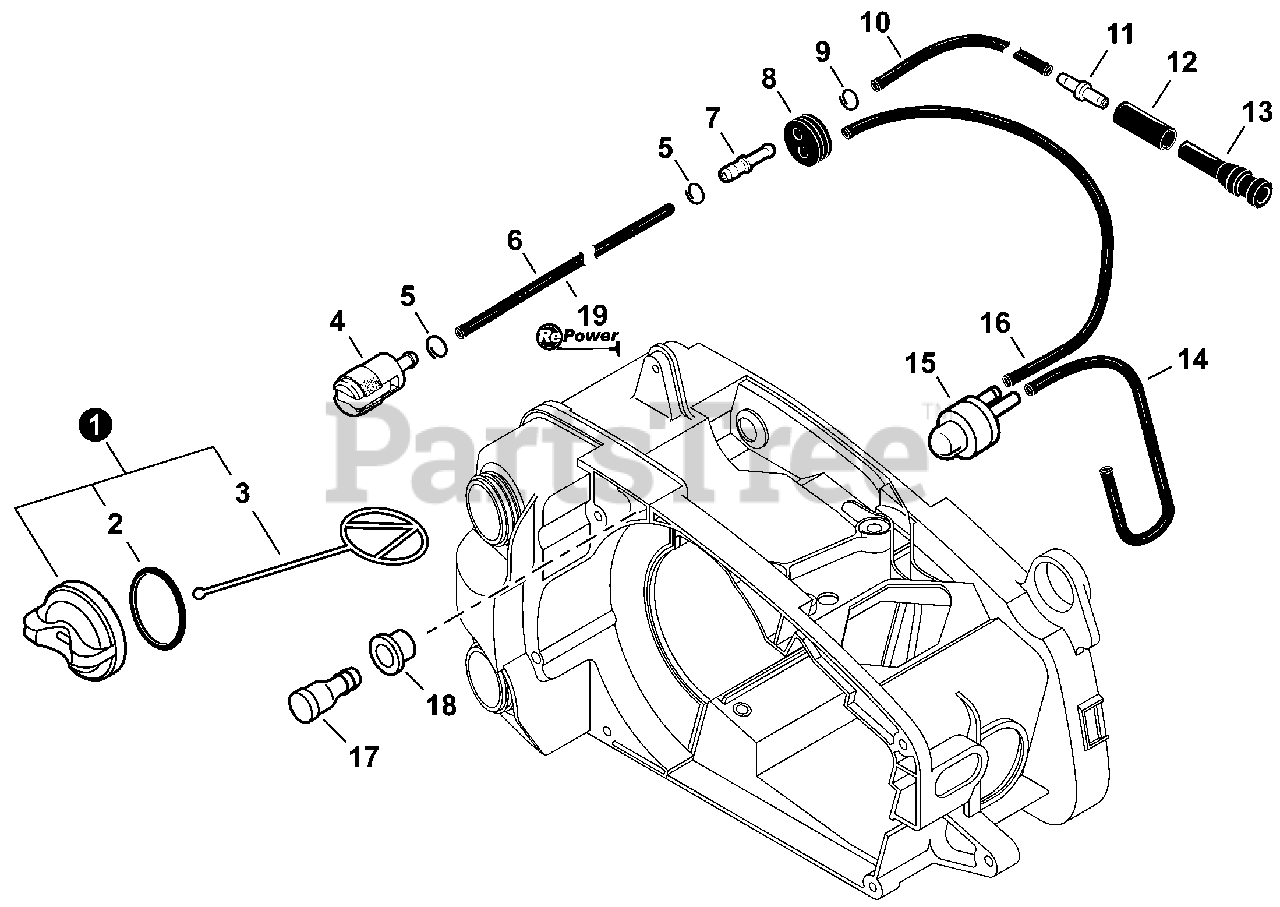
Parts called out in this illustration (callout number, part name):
1	CAP ASSY, FUEL - ORANGE
3	CONNECTOR, CAP L= 60 MM
4	FILTER, FUEL
5	CLIP Ø6
6	PIPE, FUEL 3×5×95
7	CONNECTOR, PIPE Ø5ר3.5
8	GROMMET, FUEL
10	PIPE, FUEL 3×5×165
11	CONNECTOR, PIPE
12	TUBE Ø6.5×8.5×18
13	PIPE, FUEL 10×6×32
14	PIPE, FUEL 2.4×5×75
15	BULB, PURGE
16	PIPE, FUEL 2.4×5×295
17	VENT ASSY
18	GROMMET, FUEL
19	BULK PIPE - 3×5 MM BLACK (4 PIECES×2 M)
